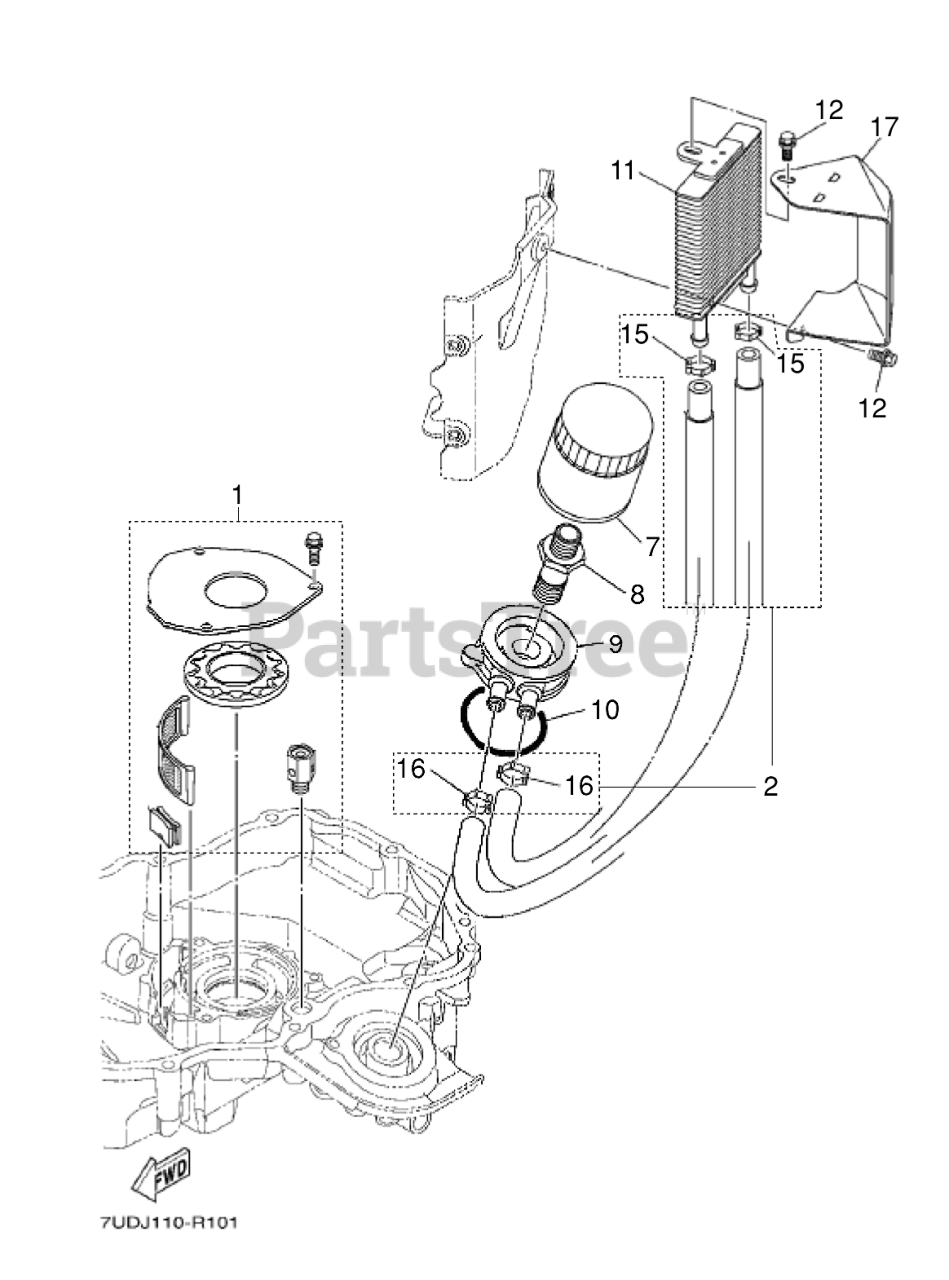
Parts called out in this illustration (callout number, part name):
2	OIL COOLER HOSE KIT
7	OIL FILTER ELEMENT ASSY YAMAHA
8	BOLT YAMAHA PN: 7UD-E7056-00
10	SEAL 1 YAMAHA PN: 7UD-E358B-00
11	OIL COOLER ASSY YAMAHA PN: 7UD
12	BOLT YAMAHA PN: 95822-06010
